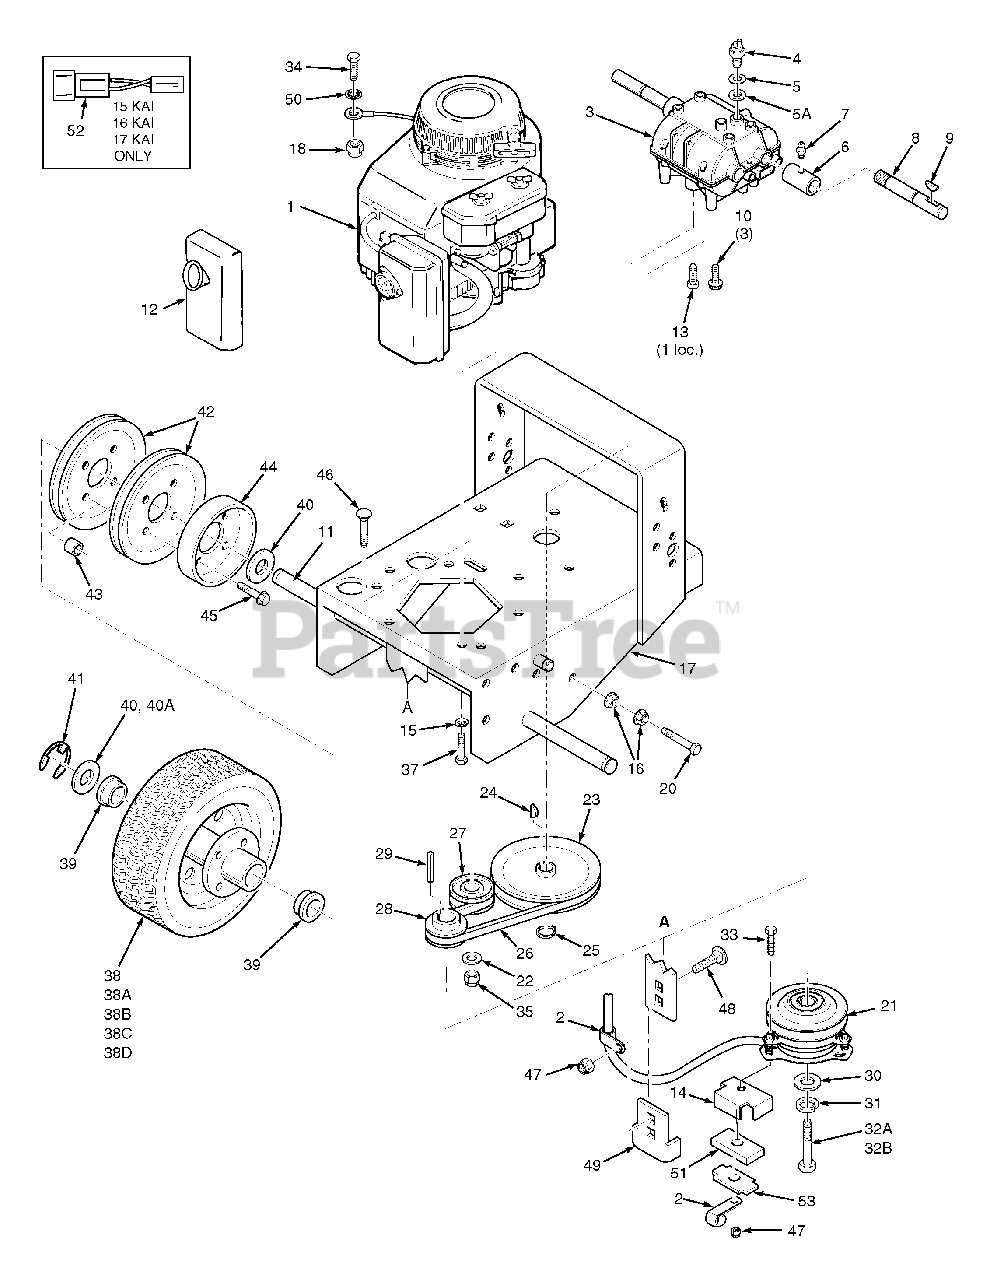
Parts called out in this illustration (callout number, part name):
1	Engine, 15HP Kawasaki
2	Cable Clamp
3	Transmission,5-speed
4	Neutral Safety Switch
5	Fibre Washer, thin
5A	Fibre Washer, thick
6	Coupler, Jackshaft
7	Grease Fitting, straight 1/4-28
8	Jackshaft
9	Key, Hi-Pro #9
10	Bolt, 5/16-18 X 3/4" Hex Head
11	Wheel Axle
12	Muffler
13	Bolt, 5/16-18 X 3/4" Hex Head
14	Backing Plate
15	Lock Wshr. 5/16"
16	Nut, 3/8-16 Serrated Flange
17	Engine Deck
18	Nut, 1/4-20 Elastic Stop
19	Nut, 5/16-18 Serrated Flange
20	Bolt, 3/8-16 x 3-3/4" Hex Head
21	Electric Clutch (Ogura)
22	Washer, 3/8" (.391 x .938 x .105)
23	Pulley, Transmission Input
24	Key, Woodruff #9
25	Retaining Ring, 5/8" Ext, Basic
26	Belt, Transmission Drive
27	Idler Pulley, Transmission
28	Pulley, Traction Drive
29	Key, 1/4 x 1/4 x 3/4"
30	Flat Washer, 7/16" Special
31	Lock Washer, 7/16"
32A	Bolt, 7/16-20 x2-1/2" Hex Head
32B	Cpsrw, M10-1.5 x55 Metric Hex Hd
33	Bolt, 5/16-18 x 1-3/4" Hex Head
34	Bolt, M8-1.25 x 1.0
35	Nut, 3/8-16 Elastic Stop
36	Flat Washer, 5/16"
37	Bolt, M8-1.25 x M25 Metric Hex Hd
38	Wheel Assembly
38A	Tire, 13 x 6.50-6, 2-ply
38B	Rim & Bearing Assembly
38C	Tire, 13 x 5.00-6 2-ply
38D	Rim Assembly
39	Wheel Bearing (OD 2.000 - 2.005)
40	Washer, 1-1/16 x 1-3/4 x 12 ga
40A	Washer, 1-1/16 x 1-1/2 x 18 ga
41	Retaining Ring, 1" Ext.- "E"
42	Pulley, Wheel Drive
43	Spacer, Wheel Pulley
44	Brake Drum
45	Bolt, 5/16-18 x 1-1/2" Serrated Flange
46	Bolt, 3/8-16 x 2" Carriage
47	Nut, 5/16-18 Elastic Stop
48	Bolt, 5/16-18 x 1" Carriage
49	Anti Rotation Bracket
50	Lock Washer Internal Tooth
51	Rubber Pad, Clutch Stop
52	Wire Harness Adapter
53	Plate, Backing
